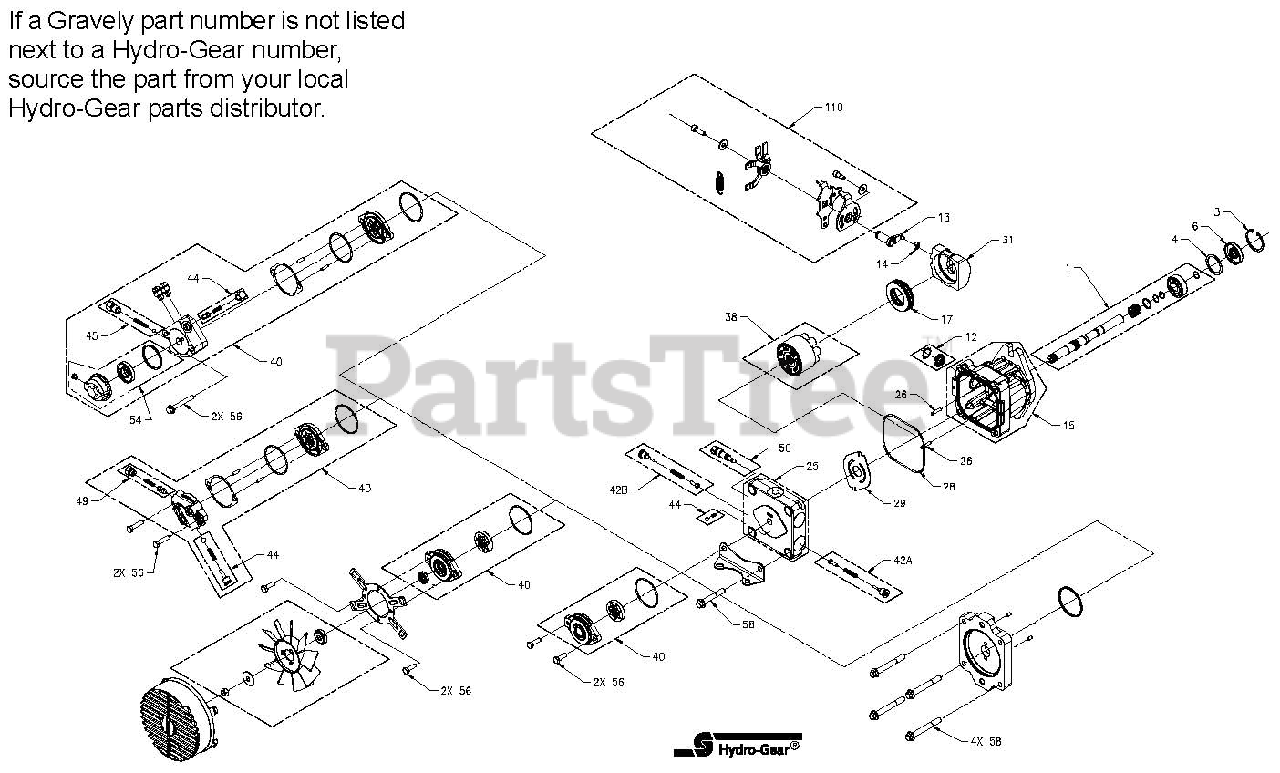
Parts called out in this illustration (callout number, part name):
1	Kit, Input Shaft
3	Ring, Retaining
4	Washer, 1.45 x 1.84 x .04
6	Lip Seal, 17 x 47 x 8
12	Kit, Trunnion Seal
13	Trunnion Arm, Taper Square
14	Slot Guide
15	Kit, Housing
17	Assembly, Thrust Ball Bearing
25	Kit, Encap
26	Pin
28	O-Ring
29	Valve Plate
31	Variable Swashplate
38	Kit, Cylinder Block
40	Kit, Charge Pump
42	Kit, Shock Valve
44	Kit, Charge Relief
45	Kit, Auxilary Relief Valve
49	Kit, Auxilary Bypass/Check Kit
50	Kit, Bypass Valve
54	Kit, Auxilary Filter Kit
56	Screw, 5/16-18 x 2.5
58	Kit, HSG Bolt
110	Kit, Return
NS	Kit, Overhaul Seal Kit
